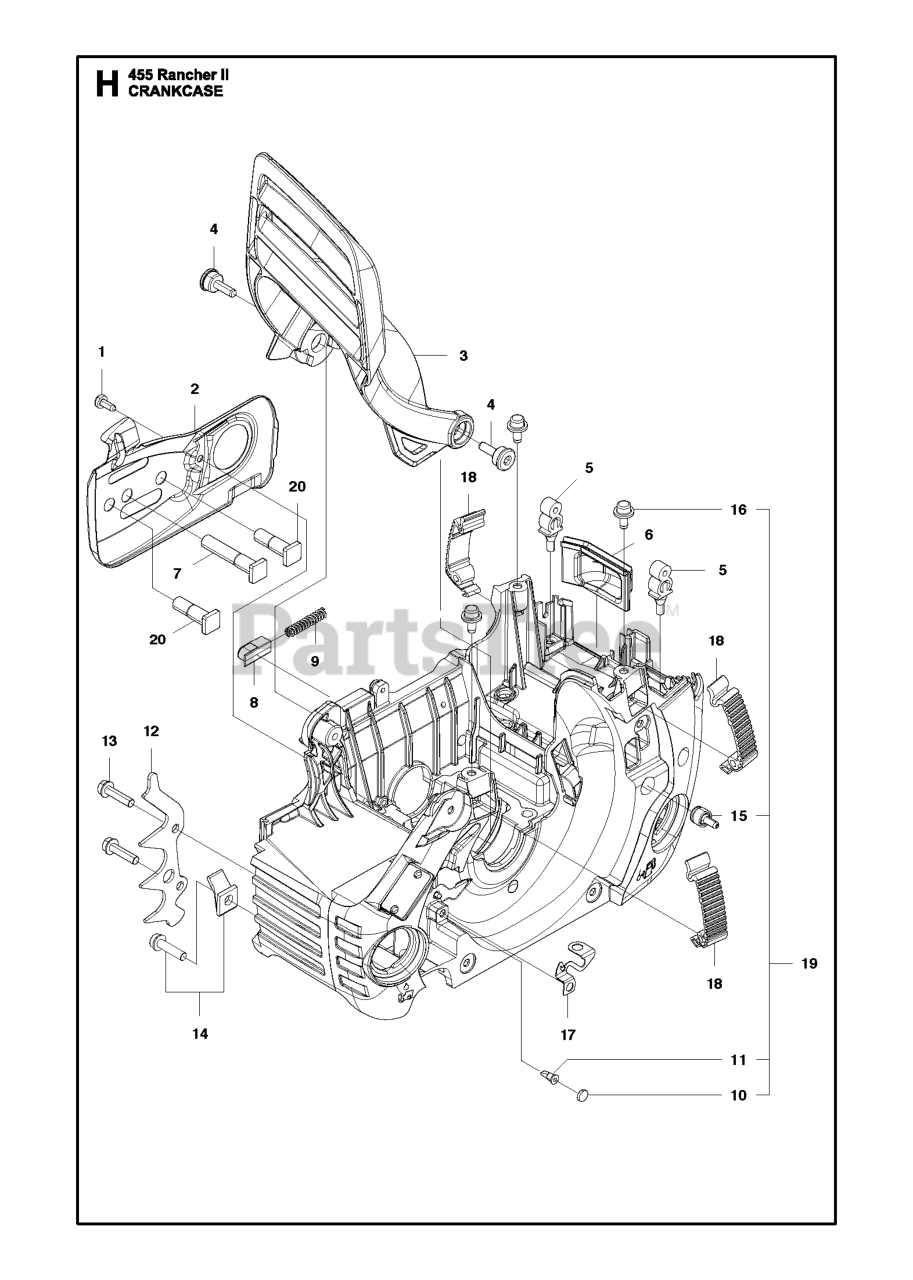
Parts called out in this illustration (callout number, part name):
1	SCREW
3	HAND GUARD
4	SCREW, HAND GUARD
7	GUIDE BOLT (X2)
9	LOCK SPRING
10	PLUG
11	VALVE-CHECK (DUCKBILL)
13	SCREW IHSCFT
14	CHAIN CATCHER
15	FUEL TANK VENT
17	GROUND PLATE
18	BUCKLE ORANGE
19	CRANKCASE ASSY
